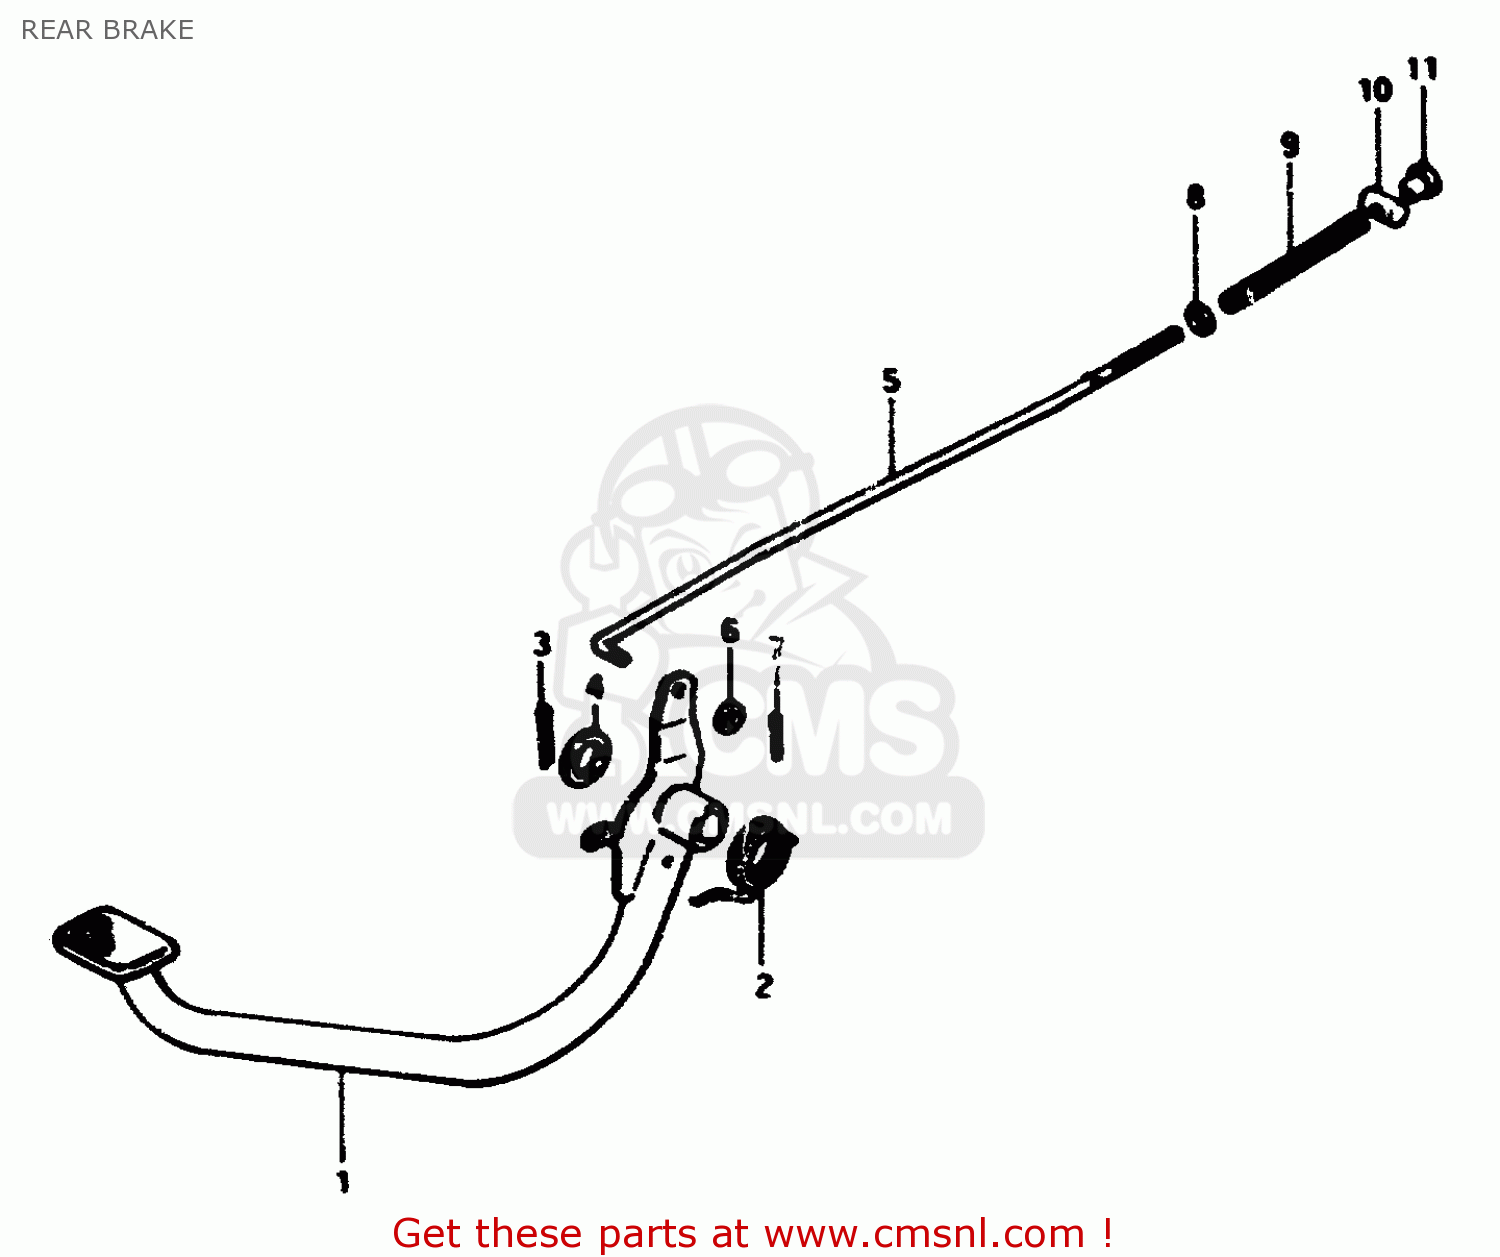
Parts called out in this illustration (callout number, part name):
1	PEDAL, BRAKE
2	SPRING
3	COTTER PIN
4	WASHER(15.5X26X2.3)
5	ROD ASSY,RR BRAKE
6	WASHER
7	PIN 20X20
8	WASHER
9	SPRING
10	PIN(11X18)
11	NUT
